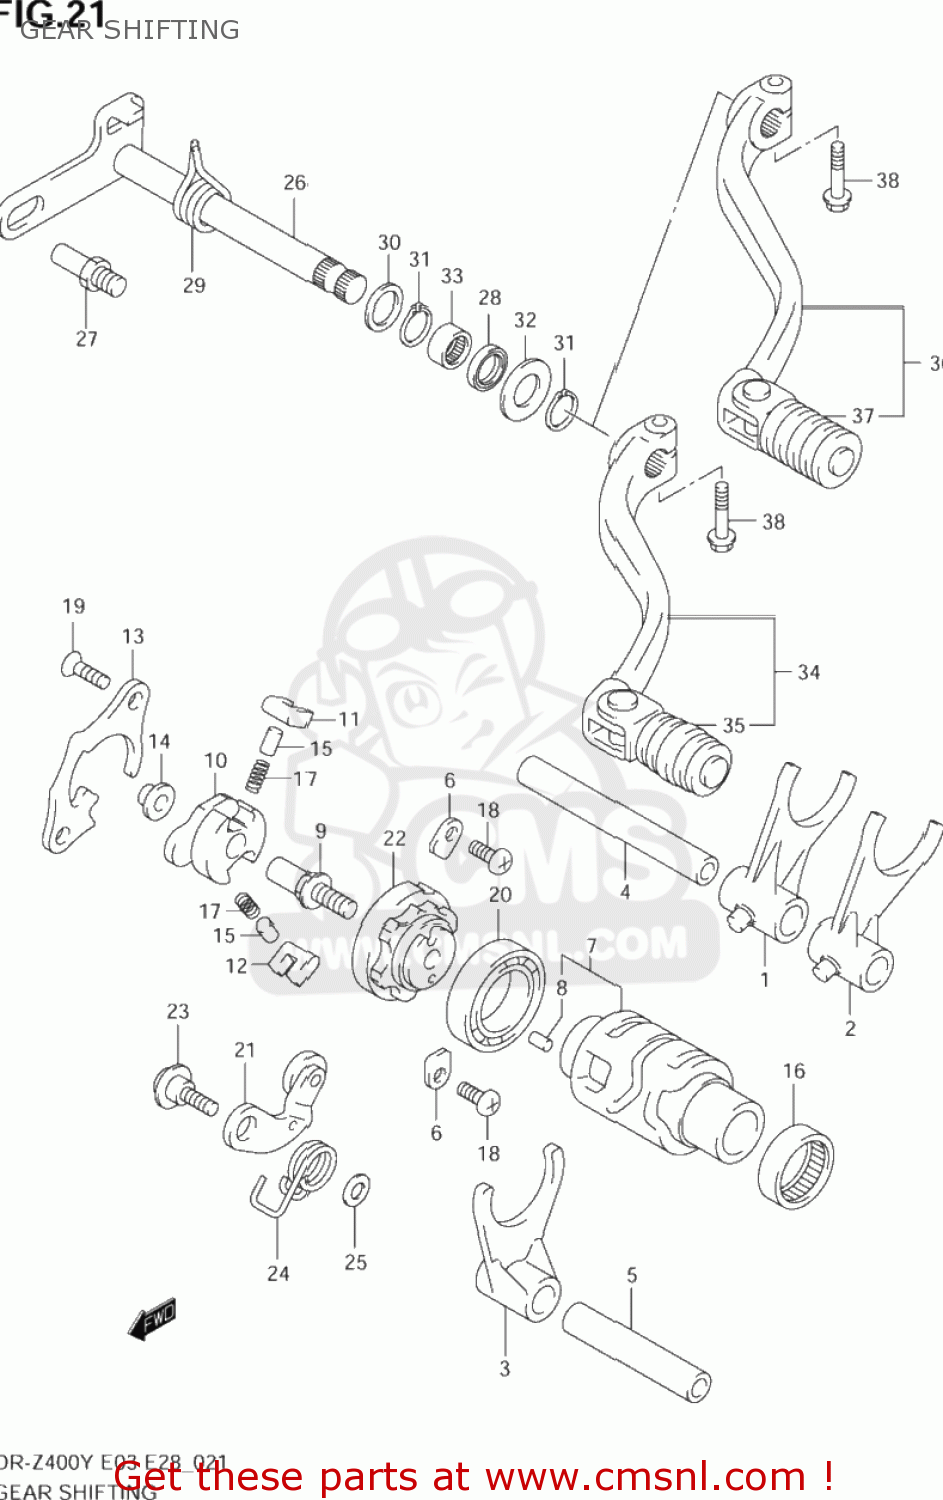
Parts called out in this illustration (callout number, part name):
1	FORK,GEAR SHIFT NO.1
2	FORK,GEAR SHIFT NO.2
3	FORK,GEAR SHIFT NO.3
4	SHAFT,GEAR SHIFT FORK
5	SHAFT,GEAR SHIFT FORK(L:60)
6	RETAINER
7	CAM,GEAR SHIFT
8	PIN
9	PIN,SHIFT CAM DRIVEN GEAR
10	SHIFTER,GEAR SHIFT CAM
11	PAWL,GEAR SHIFT NO.1
12	PAWL,GEAR SHIFT NO.2
13	LIFTER,GEAR SHIFT PAWL
14	SPACER(7X10X5)
15	PIN(5X8)
16	BEARING(25X32X12)
17	SPRING
18	BOLT(6X12)
19	SCREW(6X12)
20	BEARING
21	STOPPER,GEAR SHIFT CAM
22	PLATE,SHIFT CAM STOPPER
23	BOLT,CAM STOPPER ARM
24	SPRING,SHIFT CAM STOPPER
25	WASHER
26	SHAFT,GEAR SHIFT
27	STOPPER,SHIFT ARM
28	SEAL,OIL(14X22X6)
29	SPRING
30	SHIM(14X20X1)
31	CIRCLIP
32	WASHER
33	BEARING(14X20X12)
34	LEVER ASSY, GEAR SHIFT
35	RUBBER,GEAR SHIFT PEDAL
36	LEVER,GEAR SHF
37	RUBBER,GEAR SHIFT PEDAL
38	SCREW
